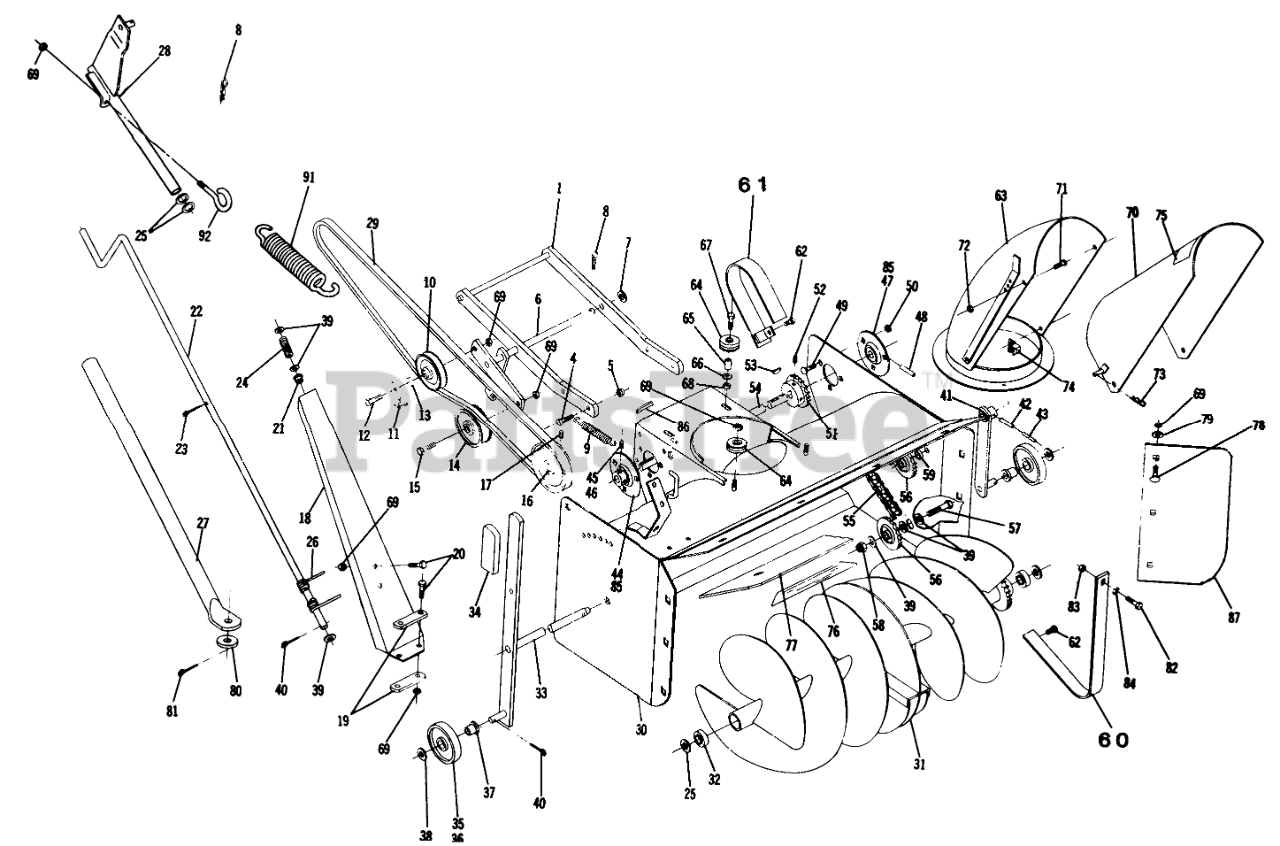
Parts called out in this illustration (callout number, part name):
1	Mounting Frame
4	Bolt 3/8-16 x 7/8
6	ASSY IDLER ARM R
7	Washer
8	Hairpin
9	SPRING R
10	PULLEY-IDLER
11	Spacer
12	Bolt Hex 3/8-16
13	Spacer
14	Idler Pulley
15	Bolt, 3/8-16 x 1/2
16	Pulley
17	Set Screw
18	Crank Support
19	Bar-Reinforcing
20	Bolt 3/8-16 x 3/4
21	NYLINER BUSHING
22	Crank
23	Cotter Pin
24	SPRING-COMPRESSION
25	Washer
26	Cable
27	Tube-Lift
28	LIFT ROD ASM
29	V-BELT
30	Wrapper Ass-y
31	Auger
32	BEARING-BALL
33	ASSY AUGER SHAFT R
34	GRIP
35	WHEEL BUSHING ASSY R
36	Wheel
37	Bushing
38	Washer
39	Washer
40	Cotter Pin
41	Wheel Support
42	ROLL PIN 1/4 X 1-1/4
43	PIN-SPIROL
44	Ball Bearing
45	Set Screw
46	Set Screw 1/4-28 x 5/16
47	Ball Bearing
48	PIN-ROLL, SPIROL
49	Bolt Hex 5/16-18 x 3/4
50	Nut-Nylok
51	SPROCKET
52	Set Screw Nylok
53	Key
54	SHAFT
55	CHAIN
56	Idler Sprocket
57	Bolt-1/2-13-1 3/4
58	Locknut-1/2-13
59	SPACER
60	Guard-Inner
61	Guard-Outer
62	SCREW
63	S/A SHROUD R
64	Roller
65	SPACER
66	Washer
67	Bolt 1/4 20 x 1 1/4
68	Nut-Nylok
69	3/8-16 E.S.
70	Deflector
71	Bolt, Round Head 1/4-20 x 1/4
72	Nut, 1/4-20
73	Hairpin
74	CLAMP
75	Decal-Caution
76	DECAL-WHEEL HORSE
77	Plate
78	Bolt 3/8-16 x 1
79	Washer
80	Washer, 5/8
81	Cotter Pin 3/16 x 1
82	Bolt-1/4-20 x 5/8
83	Nut 1/4-20 Keps
84	Washer
85	FLANGE
86	KEY-STRAIGHT
87	Plate
88	Bolt Hex 5/16-18
89	Nut, 5/16-18
90	Decal-Safety
91	SPRING
92	EYEBOLT
